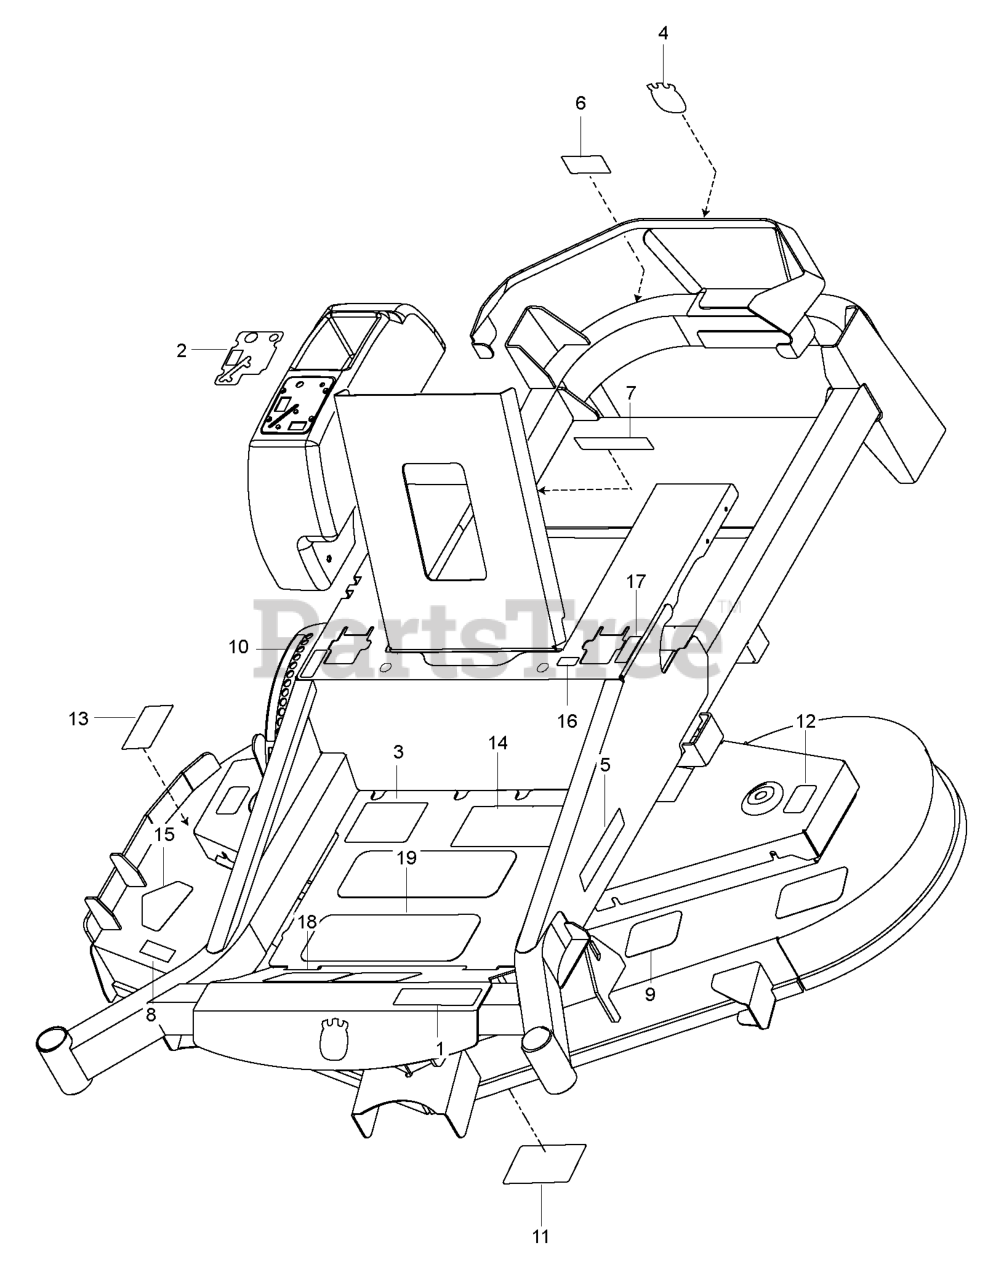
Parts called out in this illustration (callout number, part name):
1	DECAL.MZ52
2	DECAL, CONSOLE HUS
3	DECAL.ZTR.STRTNGINST.REMOTECHK
4	DECAL.AUGER.HUSQ.CROWN.SNOW
5	RP.DECAL.BADGE.170MM.TEXTLOGO
6	DECAL, BELT DRIVE
7	EURO DECAL-BATTERY WARNIN6
8	DECAL, EURO SEVERING
9	DECAL, BELT ROUTING
10	DECAL, HEIGHT ADJUST
11	DECAL, SERVICE
12	DECAL.DECK.6MIL.EURO.NOSTEP
13	DECAL.DECK.6MIL./DEF.SHLD.WARN
14	DECAL.ZTR.WARNING.SMARTIGNITIN
15	DECAL, DECK DEFLECTOR, WARNING
16	DECAL.STR.S.T.SYSMBOLONLY.2014
17	DECAL.ZTR.MOTCONTRL.SYMBOL.HUS
18	ANTI-SKID PAD
